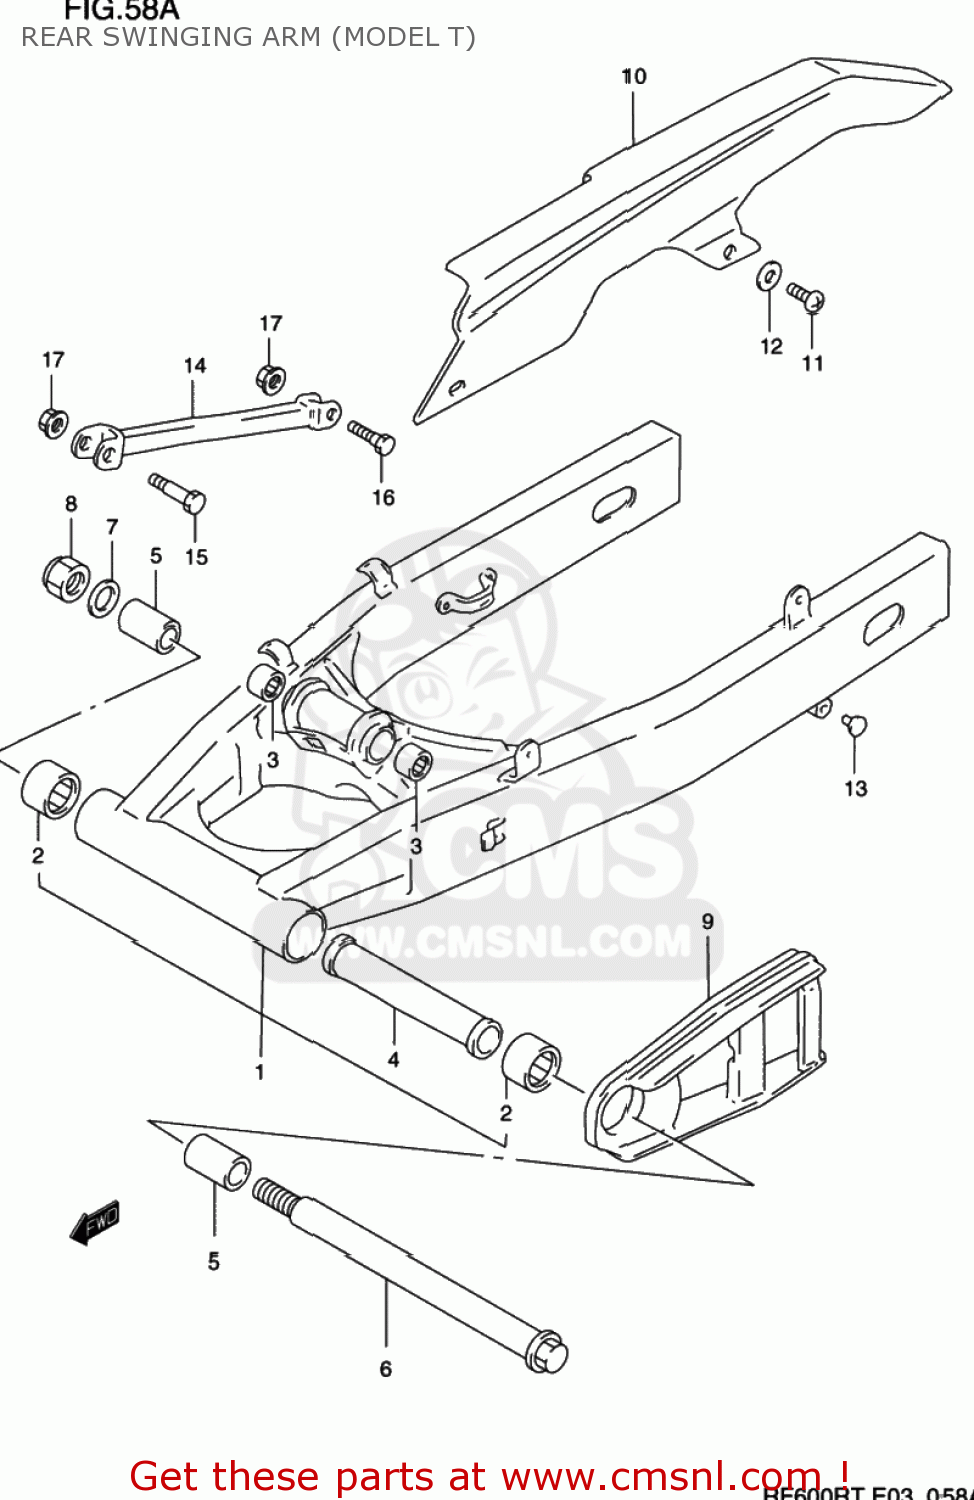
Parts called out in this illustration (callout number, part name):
1	SWING ARM ASSEMBLY,REAR
2	BEARING(25X33X35)
3	BEARING(17X24X25)
4	SPACER,REAR SWING ARM PIVOT
5	SPACER,RR SWGARM PIVOT
6	SHAFT,REAR SWING ARM
7	WASHER (18.2X28X2.6)
8	NUT
9	BUFFER,CHAIN TOUCH DEFENSE
10	CASE,CHAIN
11	SCREW 6X12
12	WASHER
13	CAP(OD:12)
14	TORQUELINK,RR
15	BOLT(10X39)
16	BOLT(10X34)
17	NUT
